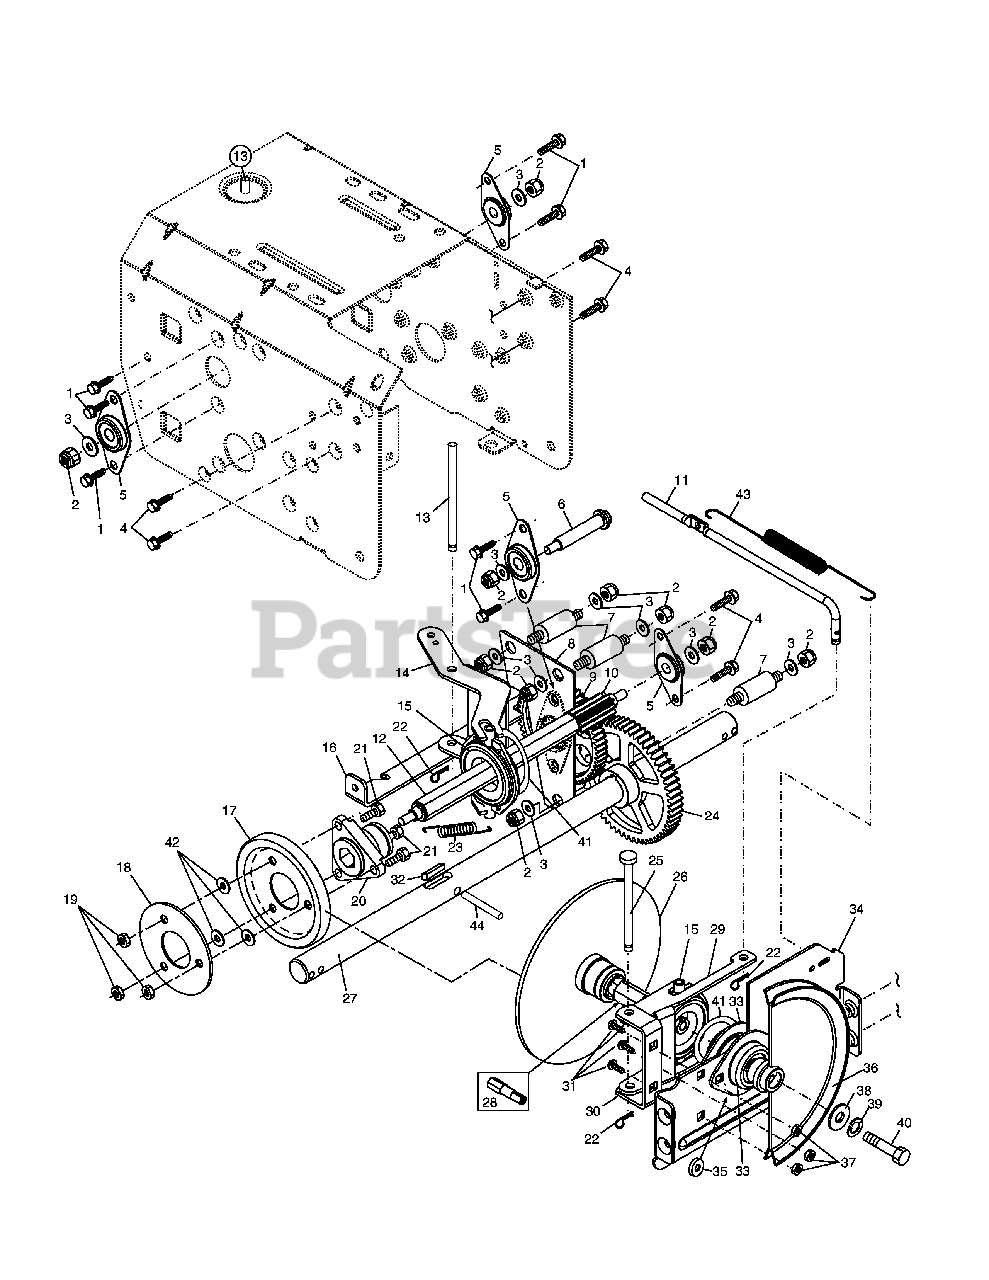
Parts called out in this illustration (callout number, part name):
1	Screw, Hex Head 5/16-18 x 5/8
2	Nut, Lock 5/16-18
3	Washer, Flat
4	Screw, Hex Head 5/16-18 x 1/2
5	Bearing, Flange
6	Shaft, Auxiliary
7	Spacer, Plate
8	Plate, Auxiliary
9	Gear, Intermediate (12/58)
10	Gear, Pinion
11	Rod, Clutch
12	Shaft, Long, Hex
13	Pin, Pivot
14	Lever, Shifter / Wheel
15	Trunnion Bearing Assembly
16	Bracket, Pivot, Shift
17	Ring, Rubber Wheel
18	Plate, Rubber Wheel
19	Nut, Lock 5/16-18
20	Hub, Rubber Wheel
21	Screw, Hex Head 5/16-18 x 7/8
22	Retainer, Hairpin
23	Spring, Bias
24	Gear, Axle (58 Teeth)
25	Pin, Pivot Lever
26	Plate Assembly, Drive
27	Shaft, Axle
28	Shaft, Short Hex
29	Lever, Shifter Plate
30	Bracket, Shifter Support
31	Bolt, Carriage 5/16-18 x 5/8
32	Key, Square 1/4 x 1/4 x 7/8
33	Bearing, Flange
34	Plate, Drive Mounting
35	Spacer, Bearing
36	Pulley, Traction Drive
37	Nut, Lock 5/16-18
38	Washer, Flat
39	Washer, Lock 5/16
40	Screw, Hex Head 5/16-18 x 3/4
41	Ring, Retaining
42	Washer .20 x 8.5 x 2.0
43	Spring, Return
44	Pin, Roll
